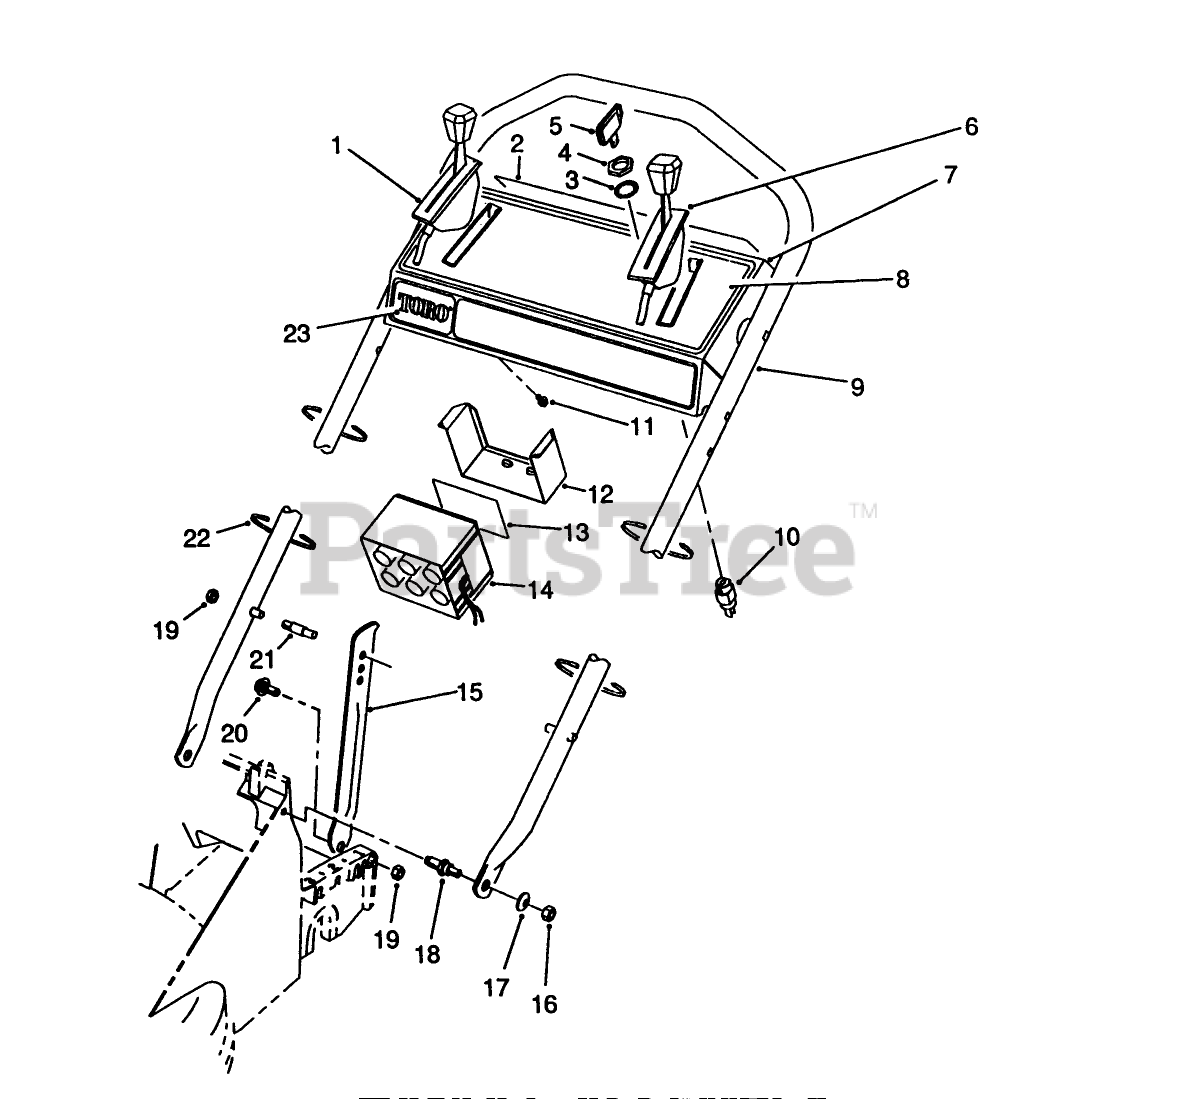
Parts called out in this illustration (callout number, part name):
1	GROUND SPEED CONTROL
2	DECAL-PANEL, DANGER
3	WASHER-LOCK
4	NUT-HH
5	KEY-IGNITION
7	PANEL W/ DECAL ASM
10	STARTER SWITCH ASM
11	SCREW-HWHTF
14	BATTERY ASSEMBLY,WET
16	NUT-LOCK, NI
17	WASHER-PLAIN
19	NUT-LOCK, NI
21	HANDLE PIN
22	TIE-CABLE
